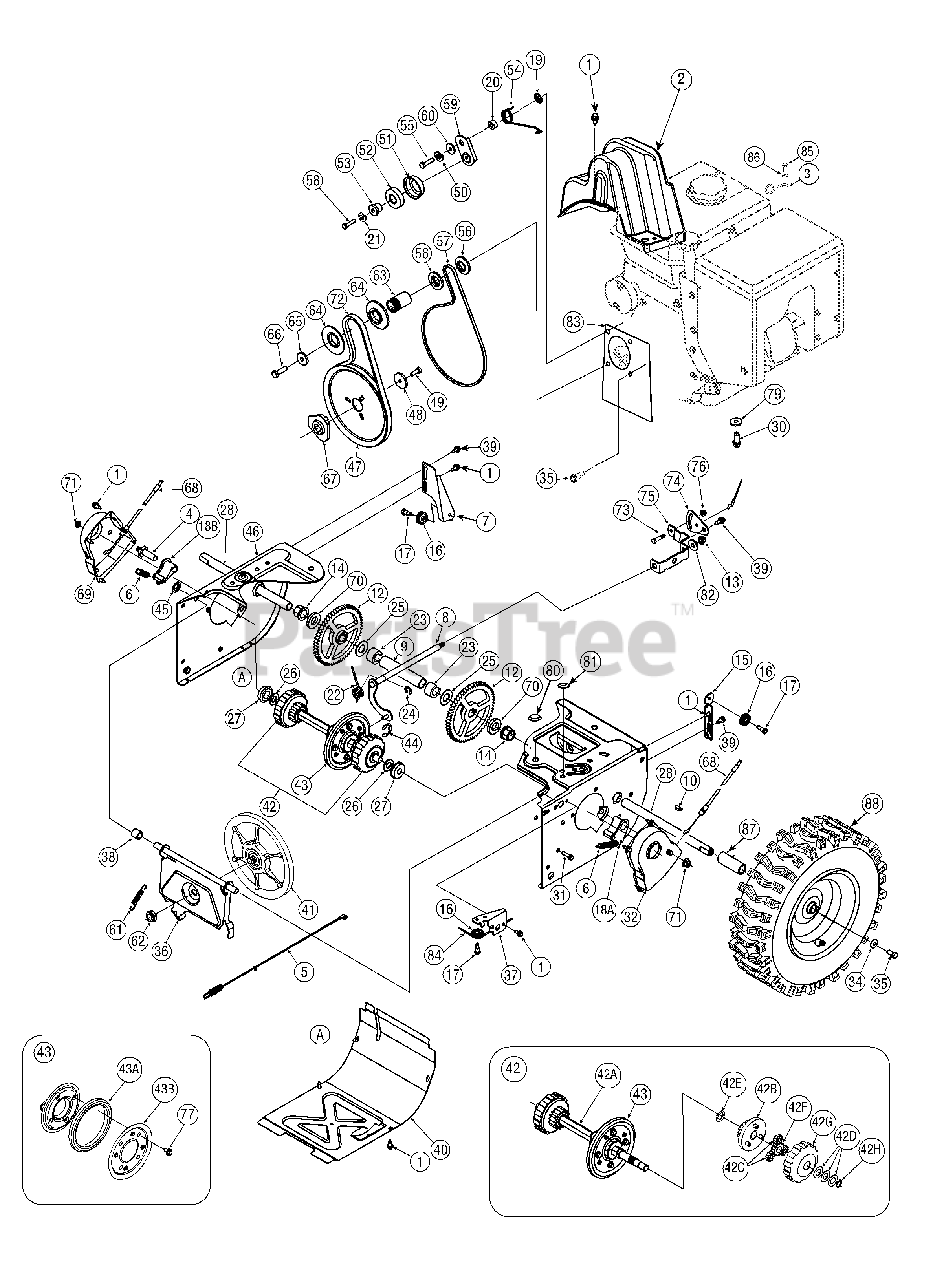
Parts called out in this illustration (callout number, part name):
1	Hex Wash Hd TT Scr. 1/4-20 x .625
2	Belt Cover (w/277 cc - 357 cc engines)
2	Belt Cover (w/208 cc engine)
3	Cable Control Wire
4	Drive Shaft Actuator
5	Drive Clutch Cable 44.83" Lg.
6	Extension Spring .5 OD x 1.71 Lg.
7	Guide Bracket - Drive Cable
8	Shift Rod Ass’y
9	Axle Support Tube
10	#9 HI-Pro Key 3/16 x 3/4 Dia HT
12	Gear, 56T
13	Flange Lock-Nut 5/16-18 Gr. F Nylon
14	Hex. Flange Bearing.751" ID
15	Guide Bracket - Auger Cable
16	Cable Guide Roller
17	Hex Shld.Scr.1/4-28 x .375
18A	Dogg Assembly - LH
18B	Dogg Assembly - RH
19	Push Nut
20	Spacer .340 x .750 x .360" Lg.
21	L-Wash 1/4 ID
22	Torsion Spring .750 ID x .968" Lg.
23	Spacer
24	Retaining Ring
25	Flat Washer .760 ID x 1.49 OD
26	Flat Washer .580 x 1.125 x .080
27	Ball Bearing
30	Hex Wash HD Tap Scr 3/8-16 x .88
31	Hex Bolt 1/4-20 x 1.00
34	Cupped Washer .345 ID x .88 OD x .060
35	Shoulder Screw .50 x .145: 5/16-24
37	Auger Cable Guide Bracket
38	Spacer .513 ID x 1.0
39	Shoulder Screw .373 x .105:TT 1/4-20
40	Frame Cover
41	Friction Wheel Disc Assembly
42	Drive Shaft Assembly (w/o Friction Wheel Ass'y)
42A	Hex Drive Shaft (500)
42B	Planetary Carrier Ass'y
42C	Gear 12T
42D	Flat Washer .58 x 1.12 x .02
42E	Flat Washer 5/8 ID x 1.0 OD
42F	Gear 18T
42G	Ring Planetary Gear Ass'y (500)
42H	Retaining Ring 1.56 diam.
43	Friction Wheel Assembly
43A	Friction Wheel Rubber
43B	Friction Plate
44	Retainer Ring
45	Cap Speed Nut 1/4 Rod
46	Wheel Drive Frame
47	Auger Pulley
48	Flat Washer .34 x 1.50 x .150
49	Hex Bolt 5/16-24 x 0.875
50	L-Wash 5/16 ID
51	Bearing Sleeve
52	Ball Bearing 20 x 47 x 14:6204:DS
53	Spacer
54	Torsion Spring .850 ID x .354" Lg.
55	Hex HD. Cap Scr. 5/16-24 x 1.25 Lg.
56	Pulley Half
57	Belt 3/8 x 34.13" Lg.(w/208 cc engine)
57	Belt 3/8 x 35.68" Lg.(w/277cc - 357cc engines)
58	Hex Bolt 1/4-20 x 1.25
59	Wheel Drive Idler Bracket
60	Shoulder Spacer
61	Extension Spring 3/8 OD x 2.50
62	Jam L-Nut 5/8-18 Gr. 5 Nylon
63	Spacer .875 ID x 1.185 OD
64	Pulley Half
65	Flat Washer .40 ID x 1.25 OD x .160
66	Hex Screw 3/8-24 x 1.25
67	Pulley Adapter
68	Steering Cable
70	Axle Spacer
71	Flange Lock-Nut 3/8-16 Gr. F Nylon
72	Belt .5 x 35.0" Lg. (w/208 cc engine)
72	Belt .5 x 37.0 (w/277cc - 357cc engines)
73	Hex Bolt 1/4-20 x .62 Gr. 5
74	Pivot Bracket
75	Shift Bracket
76	Flange Lock-Nut 1/4-20 Gr. F Nylon
77	Hex Wash. Hd. TT Scr. 1/4-14 x .625
79	Flat Washer .38 x 1.38 x .125 (Rear left hole)
80	Plug 1/2"
81	Plug 3/8"
82	Flat Washer .469 x .875 x .105
83	Cover Plate (optional)
84	Auger Clutch Cable 47.23" Lg.
85	Hex. Hd. Cap Scr. M8-1.25:20 Gr. 8
86	Flat Washer .330 ID x .630 OD x .0635
87	Spacer
88	WHEEL ASS’Y 15 x 5 x 6 LH X-Trac Gray
88	WHEEL ASS’Y 15 x 5 x 6 RH X-Trac Gray
88	WHEEL ASS’Y 16 x 4.8 x 8 LH X-Trac - Gray
88	WHEEL ASS’Y 16 x 4.8 x 8 RH X-Trac - Gray
88	WHEEL ASS’Y 16 x 6.5 x 8 LH X-Trac - Gray
88	WHEEL ASS’Y 16 x 6.5 x 8 RH X-Trac - Gray
